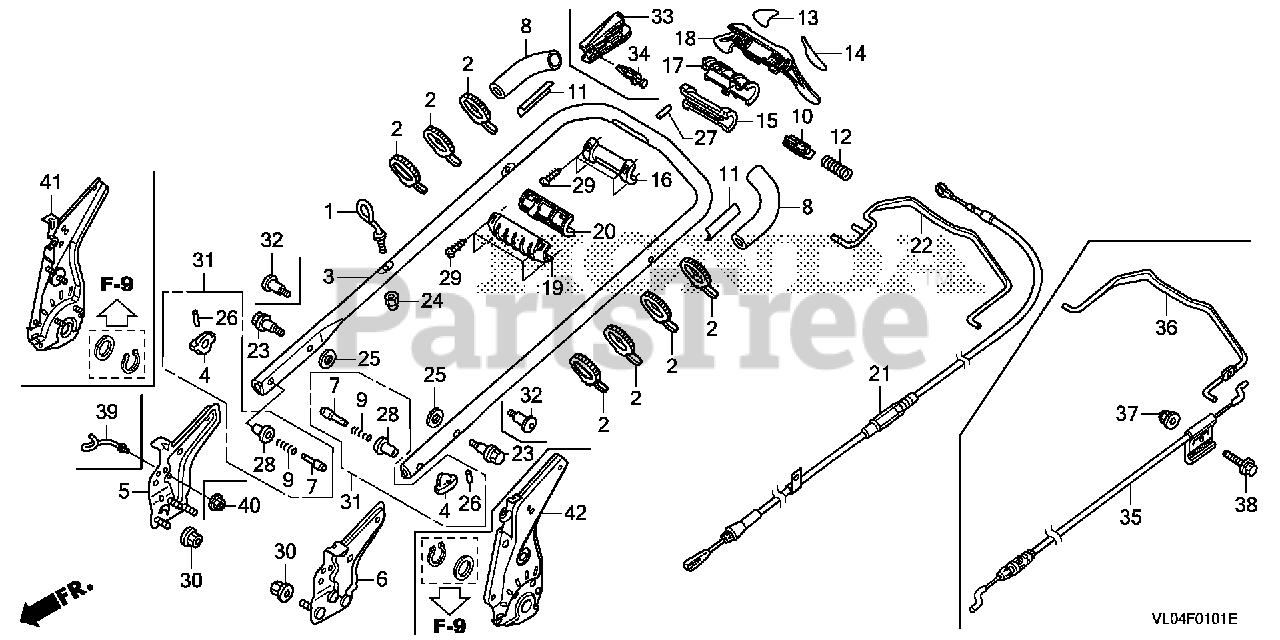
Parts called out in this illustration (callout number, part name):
1	GUIDE, ROPE
2	TIE, CABLE (157.5MM)
3	PIPE, HANDLE *NH105* (MAT BLACK)
4	GRIP, HANDLE JOINT *NH164* (GRIP GRAY)
7	PIN (8MM)
8	GRIP, HANDLE
9	SPRING, HANDLE ADJUSTING
10	LEVER, SELECT
11	HOLD, GRIP
12	SPRING, SELECT LEVER
13	GRIP, R. PAD
14	GRIP, L. PAD
15	BRACKET, GRIP (UPPER)
16	BRACKET, GRIP (LOWER)
17	COVER, BRACKET (UPPER)
18	GRIP, CLUTCH (UPPER)
19	GRIP, CLUTCH (LOWER)
20	COVER, BRACKET (LOWER)
21	CABLE, CLUTCH
24	NUT, NYLON LOCK (6MM)
25	WASHER (25MM)
26	PIN, COILED (2X12)
27	ROLLER (5X37.3)
27	ROLLER (5X37)
28	COLLAR, HANDLE HEIGHT ADJUSTING
29	SCREW, TAPPING (4X12)
30	NUT, FLANGE (8MM)
32	BOLT, SPECIAL (8X32)
33	STOPPER, LEVER
35	CABLE, BRAKE
36	LEVER, BRAKE *NH105* (MAT BLACK)
37	NUT, NYLON LOCK (6MM)
38	BOLT, FLANGE (6X45)
41	STAY, R. HANDLE
42	STAY, L. HANDLE
